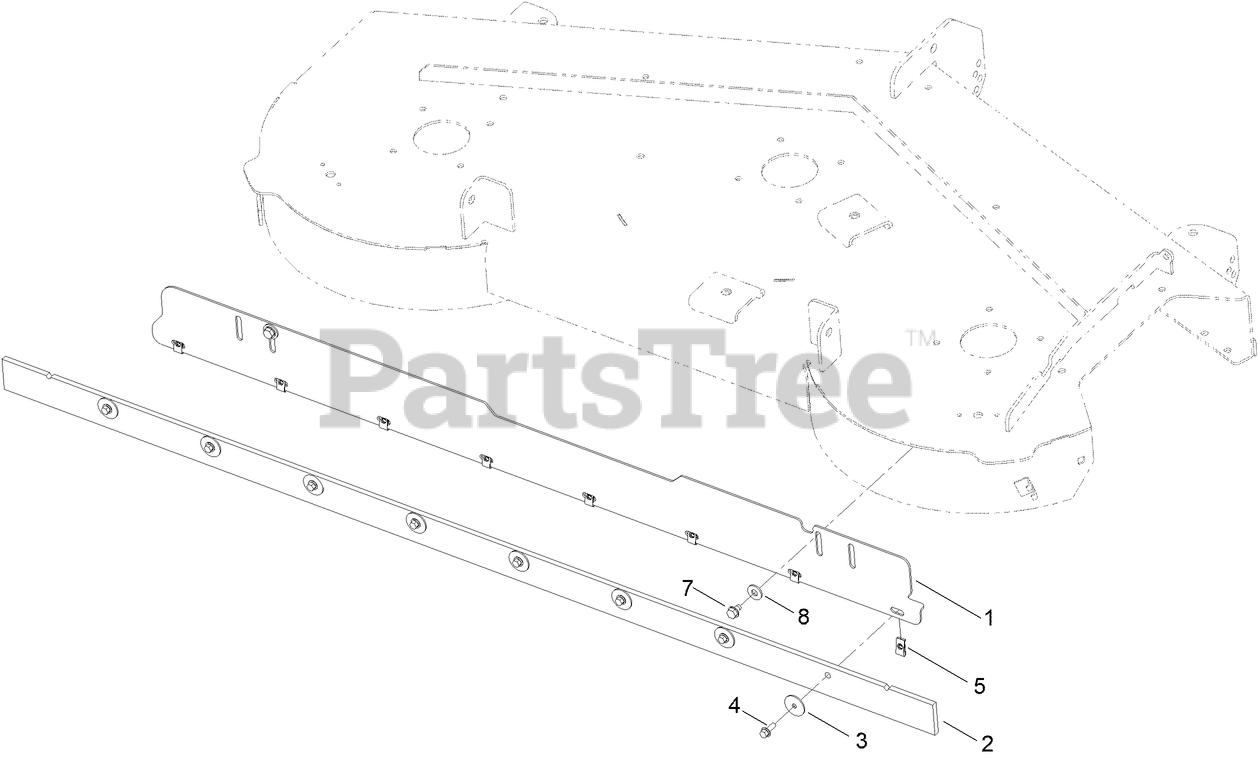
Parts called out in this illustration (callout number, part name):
1	BRACKET-STRIPING 54/60"
3	WASHER-FLAT
4	SCREW-HHF
5	NUT-SPEED
7	SCREW-HWH, THD ROLL
8	WASHER-FLAT
